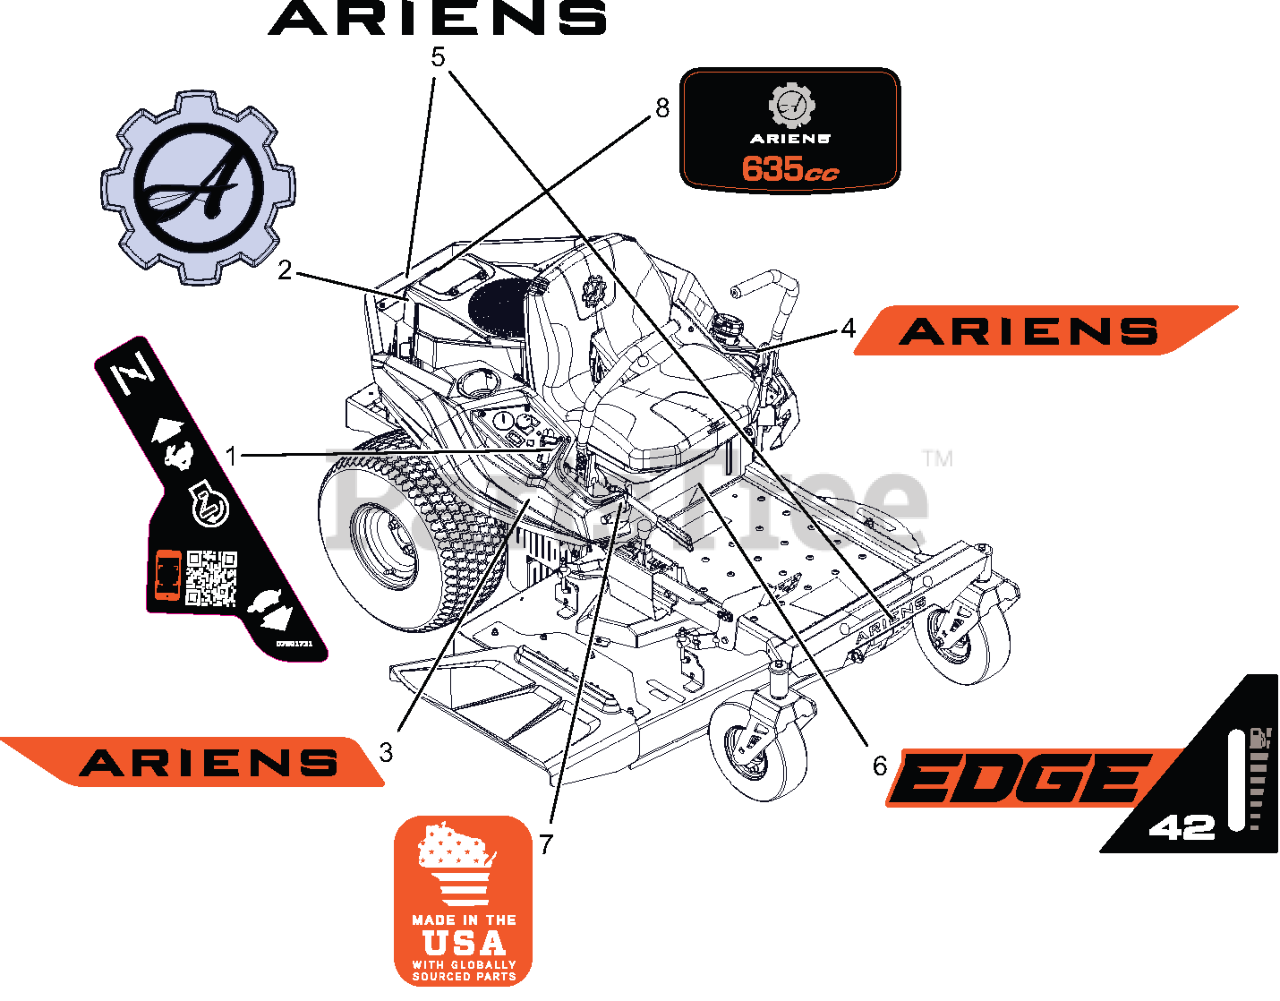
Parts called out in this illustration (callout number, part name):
1	DECAL- THROTTLE CONTROL EDGE
2	DECAL- ARIENS GEAR BADGE
3	DECAL- ARIENS (FENDER RH)
4	DECAL- ARIENS (FENDER LH)
5	DECAL- ARIENS 9.625" BLACK
6	DECAL- EDGE 42 KICKPLATE
7	DECAL- MADE IN USA
8	DECAL, ARIENS 653CC
